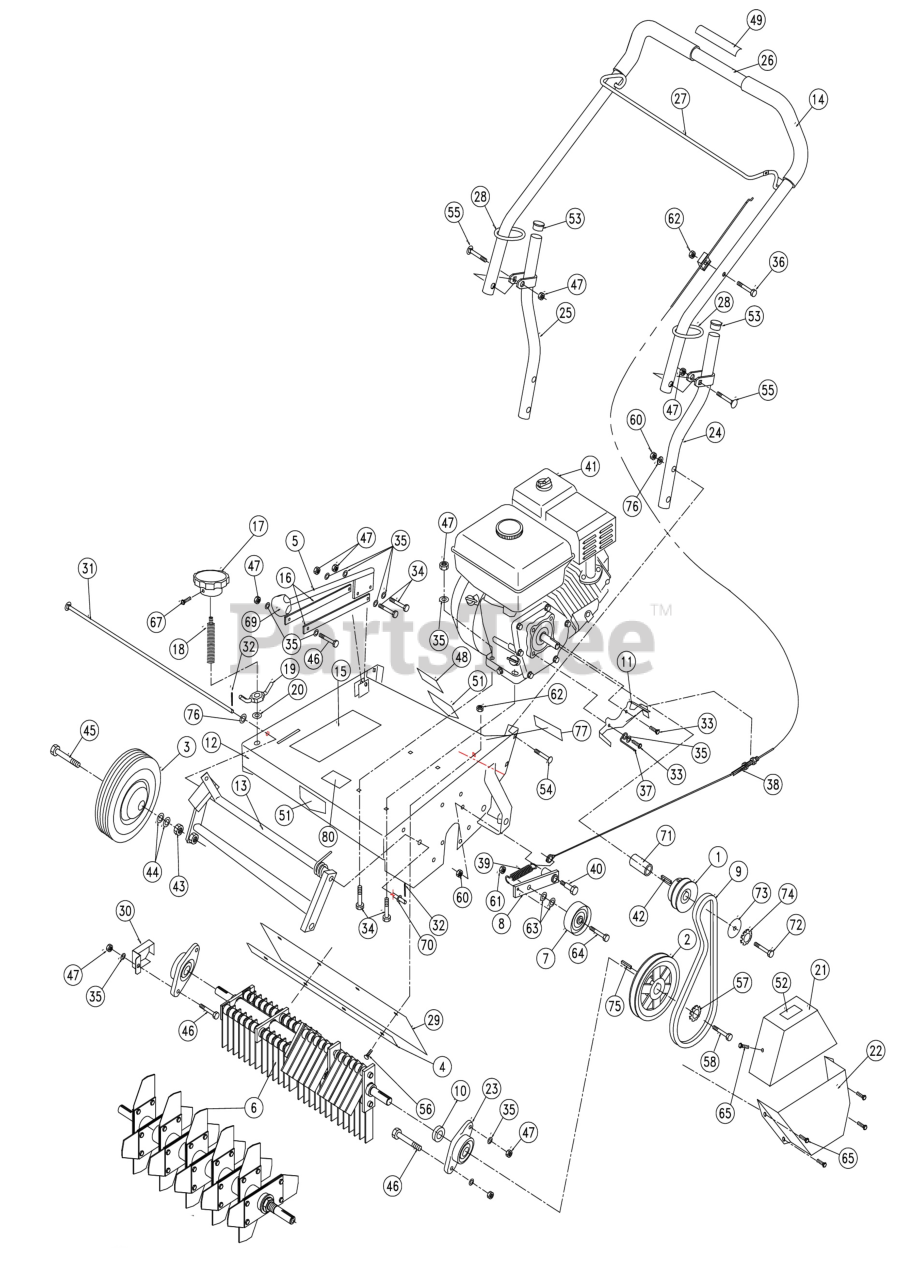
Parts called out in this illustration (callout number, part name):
1	PULLEY 3.0" X 3/4"
2	PULLEY 5.5" OD X 3/4" BORE
3	WHEEL 8" X 0.5" BRG
4	BAR STRAP DEFLECTOR
5	ROD HEIGHT
6	REEL FLAIL ASSY 9" (SEE ACCESSORY PRICELIST)
7	PULLEY IDLER 2.75" OD X 3/8" BORE
8	ARM IDLER WA
9	BELT 5L X 34"
10	SPACER REEL PULLEY
11	BRACKET BELT FINGER
12	SEE: 350235-S
13	FRAME HEIGHT FRONT
14	GRIP HANDLE 1" X 13" FOAM
15	LABEL INSTRUCTIONS CR
16	BAR LINK HEIGHT
17	KNOB HAND
18	STUD 3/4"-10 X 5 1/2" PLTD
19	LOCKNUT WA
20	WASHER 3\4" NYLON
21	GUARD BELT TOP
22	GUARD BELT BOTTOM
23	BEARING 3/4" CAST FLANGE W/ZERK
24	HANDLE LOWER LH
25	HANDLE LOWER RH
26	SEE: 350375
27	BAIL CLUTCH
28	LOOP FOLDING HANDLE PR
29	DEFLECTOR RUBBER
30	GUARD SHAFT
31	PIN LIFT FRONT 3/8" X 21 3/16" LONG
32	PIN HAIR 1/4" Z/P
33	SCREWCAP 5/16"-24X3/4" HCS G5 ZP
34	SCREWCAP 5/16"-18X1 1/2" HCS ZP
35	WASHER 1/4" FLAT Z/P
36	SCREWCAP 1/4"-20X1 1/2" HCS ZP
37	FINGER BELT WIRE
38	CABLE CLUTCH REEL
39	SPRING EXTENSION
40	BOLT SHOULDER 1/2" X 1"
41	ENGINE HONDA 5HP
42	KEY 3/16" SQ X 1"
43	NUT LOCK 1/2"-13 HVY ZP
44	WASHER 1/2" SAE Z/P
45	SCREWCAP 1/2-13 X 3" Z/P
46	SCREWCAP 5/16"-18X1 1/4" HEX ZP
47	NUT LOCK 5/16"-18 HEX Z/P
48	LABEL DANGER FLYING DEBRIS
49	LABEL CLUTCH VQ
51	LABEL WARNING OPEI
52	LABEL DANGER
53	PLUG TUBE INSERT 1" OD
54	BOLT CARRIAGE 3/8"-16 X 1 3/4" ZP
55	BOLT CARRIAGE 5/16"-18 X 1 3/4" ZP
56	SCREWCAP 1/4"-20 X 1" HCS ZP
57	WASHER LOCK 3/8" TWISTED TOOTH
58	SCREWCAP 3/8"-16 X 1" HCS ZP
60	NUT LOCK 3/8"-16 HEX
61	NUT LOCK 3/8-16 LT WT THIN ZP
62	NUT LOCK 1/4"-20 HEX Z/P
63	WASHER 5/16" FLATWASHER Z/P
64	SCREWCAP 3/8" - 16 X 1/2" HCS ZP
65	SCREW SM 1/4" X 3/4" DRILL PT.
67	SCREW MACHINE #10-24 X 2" HWF ZP
69	KNOB SHIFT
70	WASHER 3/8"SAE 13/32"X13/16"X1/16"
71	SPACER CRANK CR HONDA
72	SCREWCAP 5/16"-24X1 1/4" GR 8 ZP
74	SCREWCAP 5/16"-24X1 1/4" GR 8 ZP
75	KEY 3/16" SQ X 5/8"
76	WASHER 3/8"FC7/16"X1"X5/64"
77	LABEL SPARK ARRESTOR
